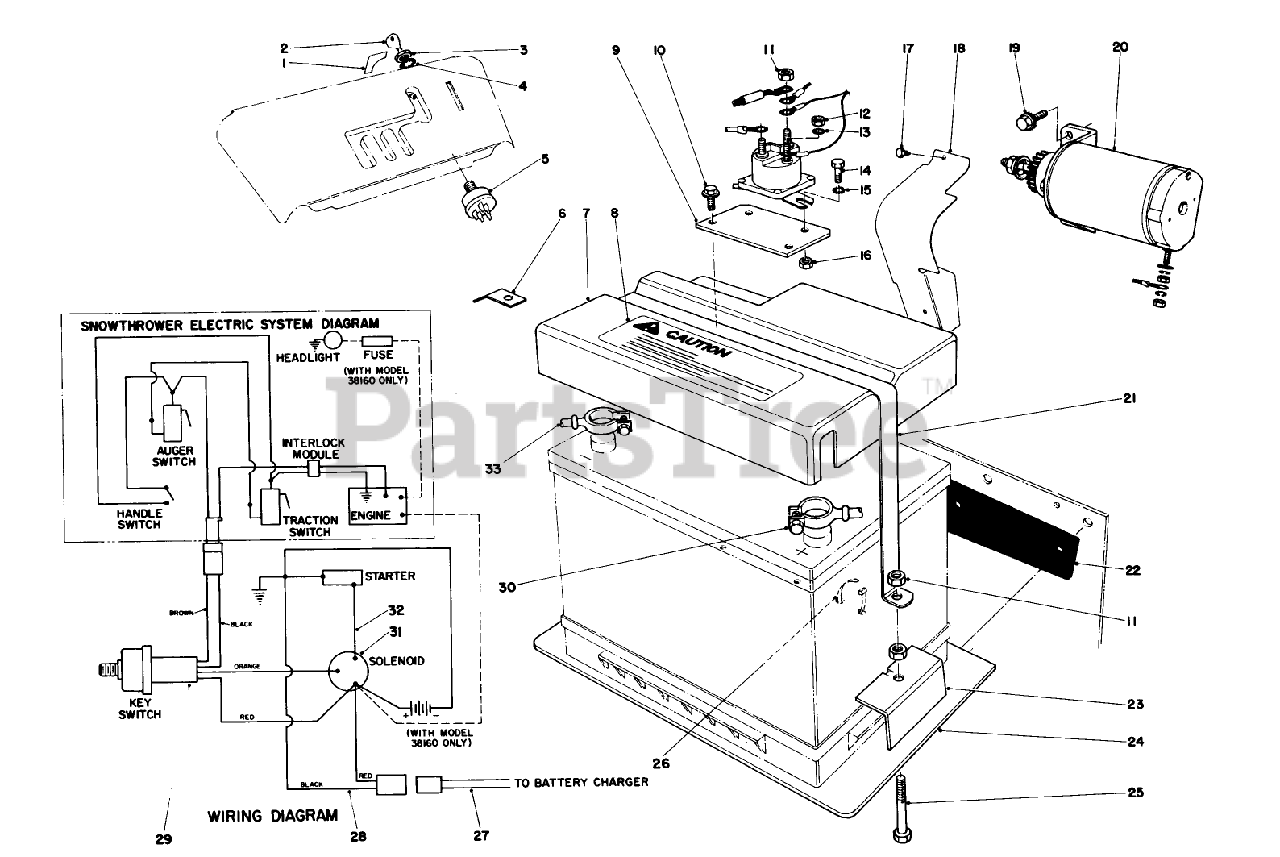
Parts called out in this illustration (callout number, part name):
4	WASHER-LOCK
10	SCREW-HWH
11	NUT-HEX
12	NUT-HEX
13	WASHER-LOCK, INT
14	SCREW-HH
15	WASHER-LOCK/EXT
16	NUT-LOCK, NI
18	BRIGGS 280265
19	5/16-18X3/4 HX HD SEM
20	Starter Motor Pinion Assy.
25	SCREW-HH
26	TIE-CABLE
27	MALE WIRE ASM
30	BATT-SOLENOID CABLE
31	SOLENOID
